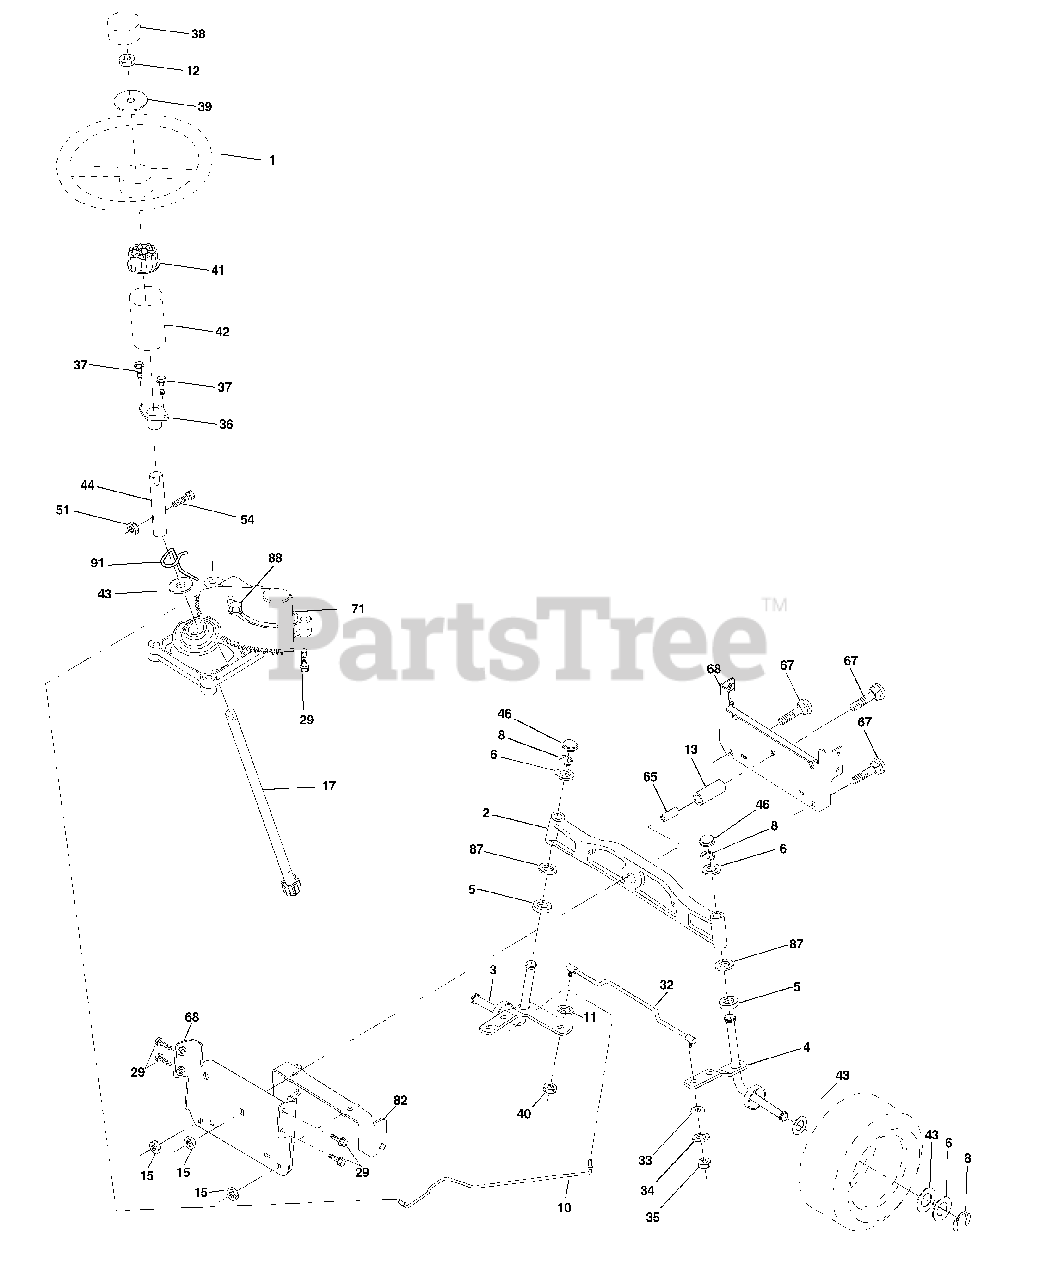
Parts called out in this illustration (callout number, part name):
1	Wheel Steering
2	Axle Asm Cast Iron LT
3	Spindle Asm LH
4	Spindle Asm RH
5	Bearing Race Thrust Harden
6	Washer 25/32 X 1-5/8 X 16 Ga
8	Ring Klip #t5304-75
10	Link Drag
11	Washer Lock Hvy Hlcl Spr 3/8
12	Nut Hex Jam Toplock 1/2-20 Unf
13	Spacer Brg. Axle Front
15	Nut Hex Flange Lock
17	Shaft Asm. Steering
29	Screw 3/8-16x.75
32	Rod Tie
33	Washer 11/32 x 3/4 x 16 Ga.
34	Washer Lock Hvy Hlcl Spr 5/16
35	Crownlock Nut 5/16-24
36	Bushing Strg
37	Screw
38	Insert Cap Strg Wh Au
39	Washer
40	Lock nut
41	Adaptor Wheel Strg
42	Boot Steering Dash
43	Washer 25/32 X 1 1/4 X 16 Ga
44	Extension Steering Shaft
46	Cap Spindle Fr Top Blk
51	Nut Crownlock 1/4-28
54	Bolt Hex 1/4-28 Unf x 1-1/4 Gr. 8
65	Brace Axle
67	Bolt Rdhd Sq 3/8-16 Unc x 2-1/4
68	Axle, Brace
71	Steering Asm.
82	Bracket Susp. Chassis Front
87	Washer Flat .781 x 1-1/2 x .14
88	Bolt Shoulder 7/16-20 Unc
91	Clip Steering
